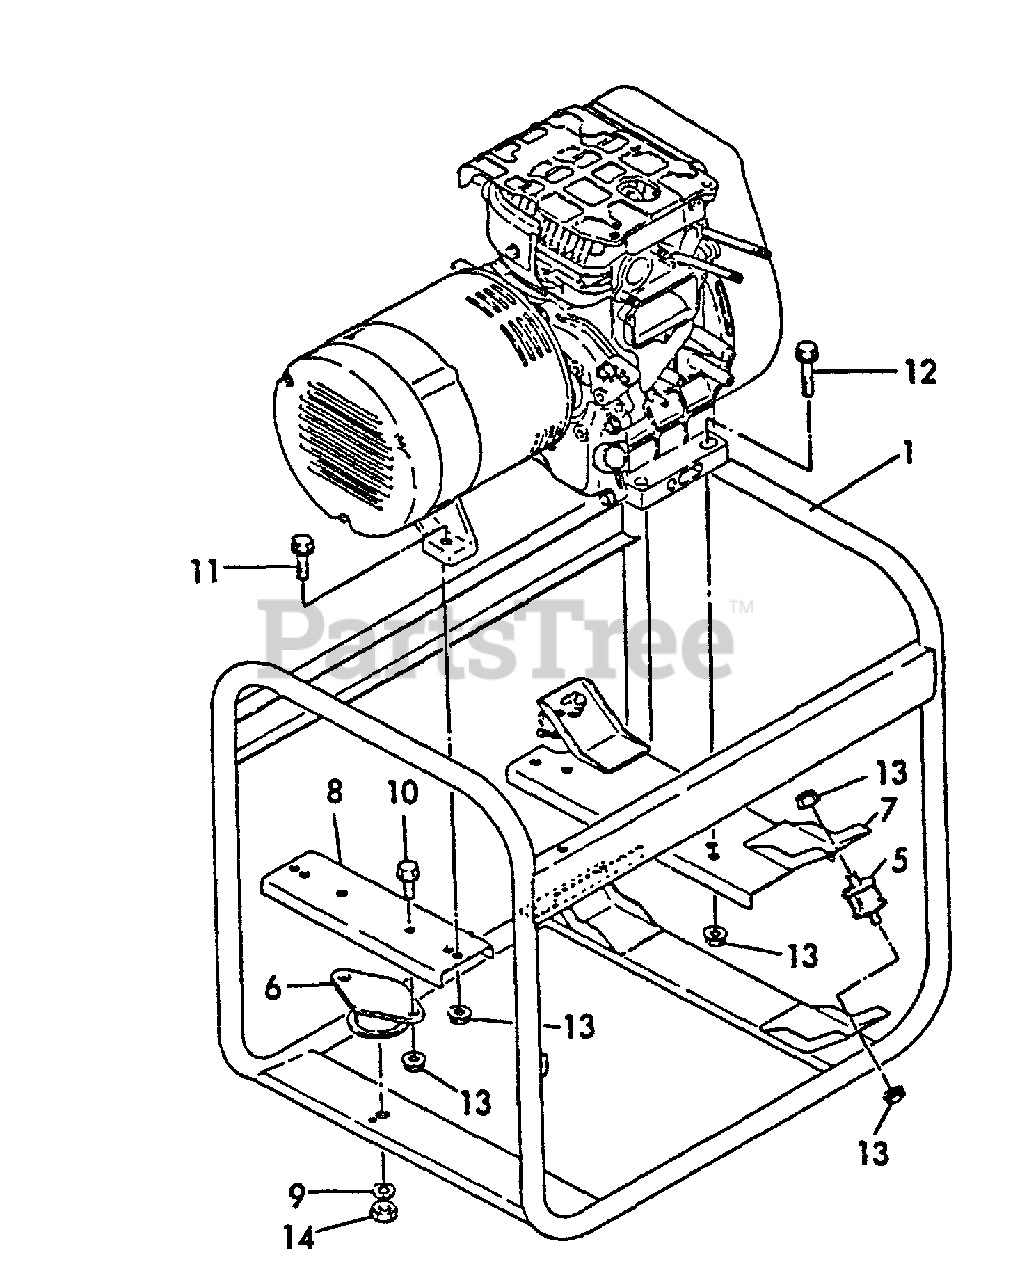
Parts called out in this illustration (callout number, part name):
1	FRAME ASSY
5	DAMPER, FRONT
6	DAMPER, REAR
7	STAY, DAMPER
8	STAY, REAR DAMPER
9	LOCKWASHER - 10
10	BOLT - 8X20 -- PLATED
11	BOLT - 8X30 -- PLATED
12	BOLT - 8X38 -- PLATED
13	NUT - 8
14	NUT - 10
